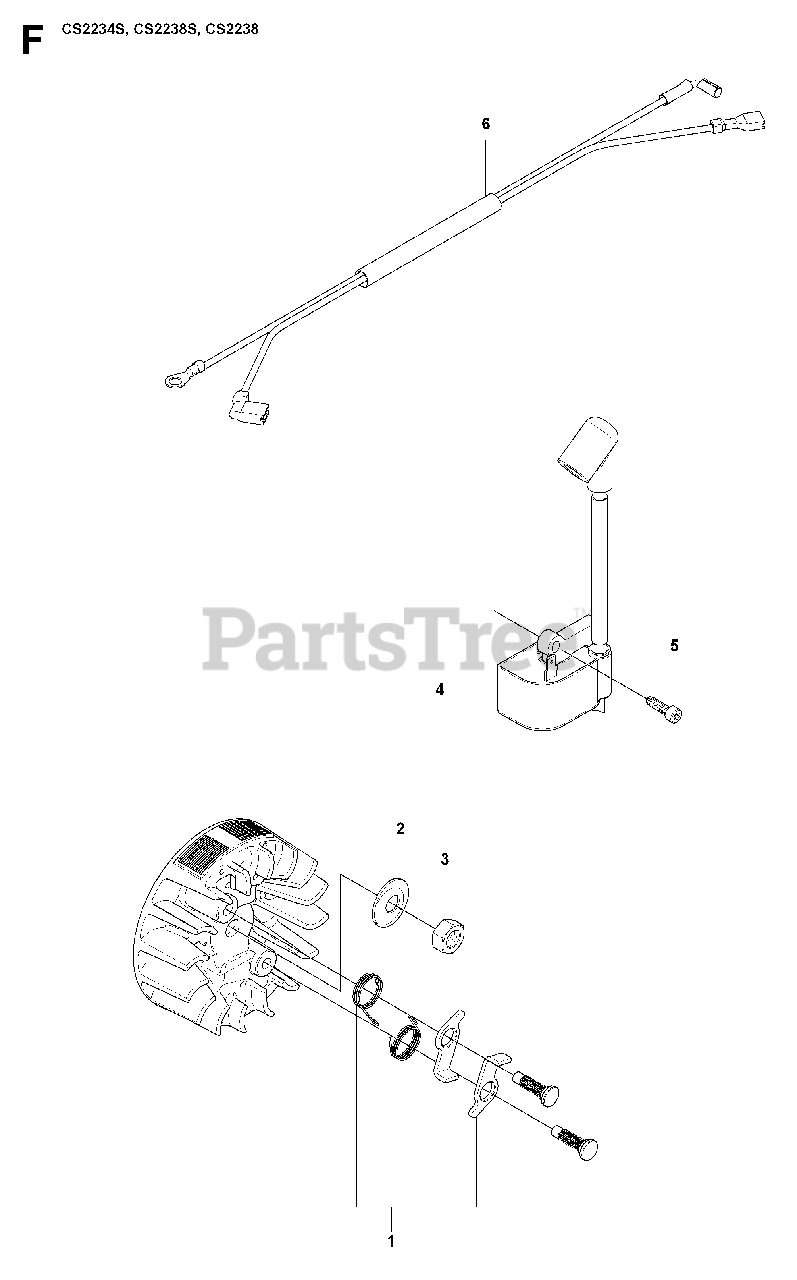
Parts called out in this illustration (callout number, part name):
1	ROTOR COMPL. 36/41
2	WASHER-FLYWHEEL
3	NUT-FLYWHEEL
4	%IGNITION MODULE
6	WIRE HARNESS ASSY
